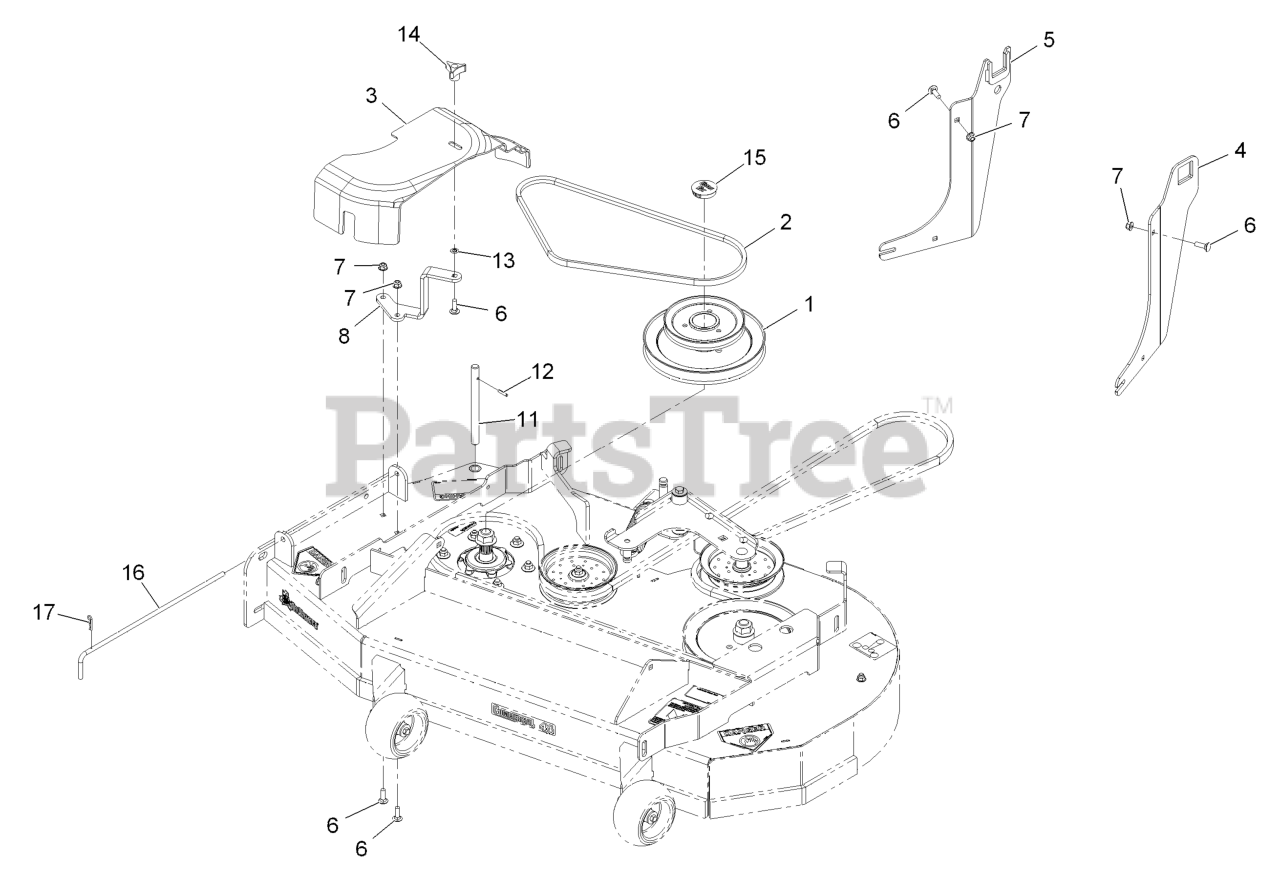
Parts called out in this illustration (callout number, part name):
1	JACKSHAFT,44 UV
2	BELT, BLOWER DRIVE 72
3	COVER-BELT, UV 44
4	BRACKET ASM, LH
5	BRACKET ASM, RH
6	BOLT-CARR
7	NUT-HF, NI
8	BRACKET-BELT COVER 44
11	SHAFT-CATCHER, GRASS
12	PIN-ROLL
13	RING-RETAINING, BOLT
14	KNOB-3 PRONG
15	PLUG, BLACK NYLON 1.75
16	PIN,CHUTE PIVOT
17	PIN-COTTER
